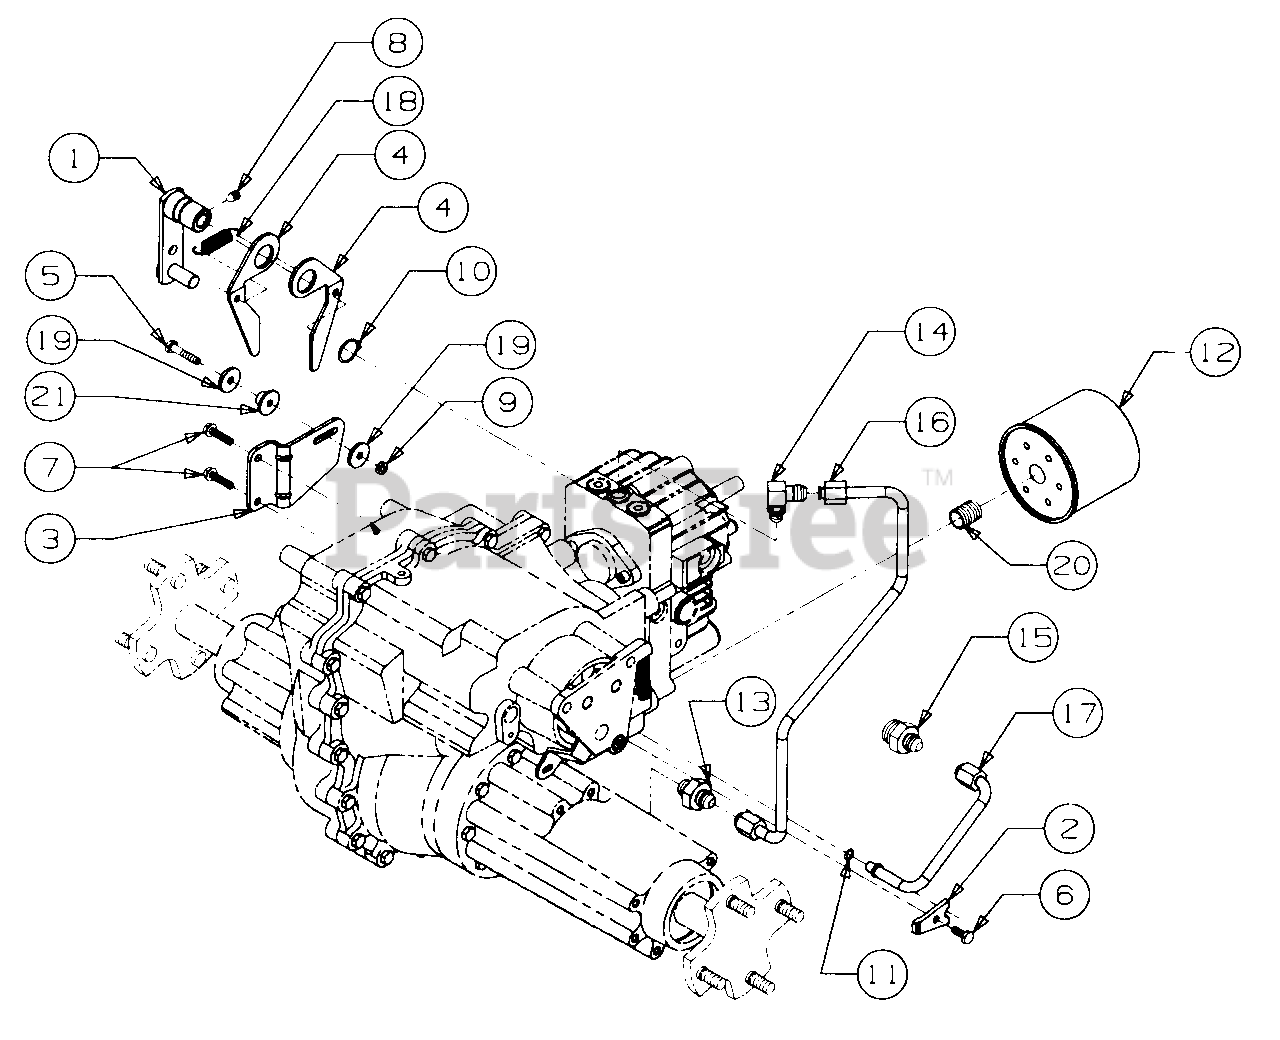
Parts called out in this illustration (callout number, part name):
1	Arm Assy, Control
2	Clamp, Single
3	Bracket, Hydro Neutral
4	Arm, Neutral
5	Screw, Hex Cap, 1/4-20 x 1.25 Lg
6	Screw, Hex Cap, 1/4-20 x .62 Lg GR5
7	Screw, Hex Wash 1/4-20 x 1.0 Lg T-Tap
8	Screw w/Patch,Set
9	Nut, Hex Top Lock, 1/4-20
10	Ring, Snap, .875 Shaft
11	O-Ring, .301 x .070 Dia
12	Filter, Oil
13	Connector, Tube 37 Deg w/O-Ring
14	Elbow, Adjustable w/O-Ring
15	Connector, Straight w/O-Ring
16	Tube, Pickup
17	Tube, Return
18	Spring, Extension, .50 OD x 1.97 Lg
19	Washer, Flat, .25 x .93 x .120 Thk
20	Nipple, Oil Filter
21	Spacer, Centering
